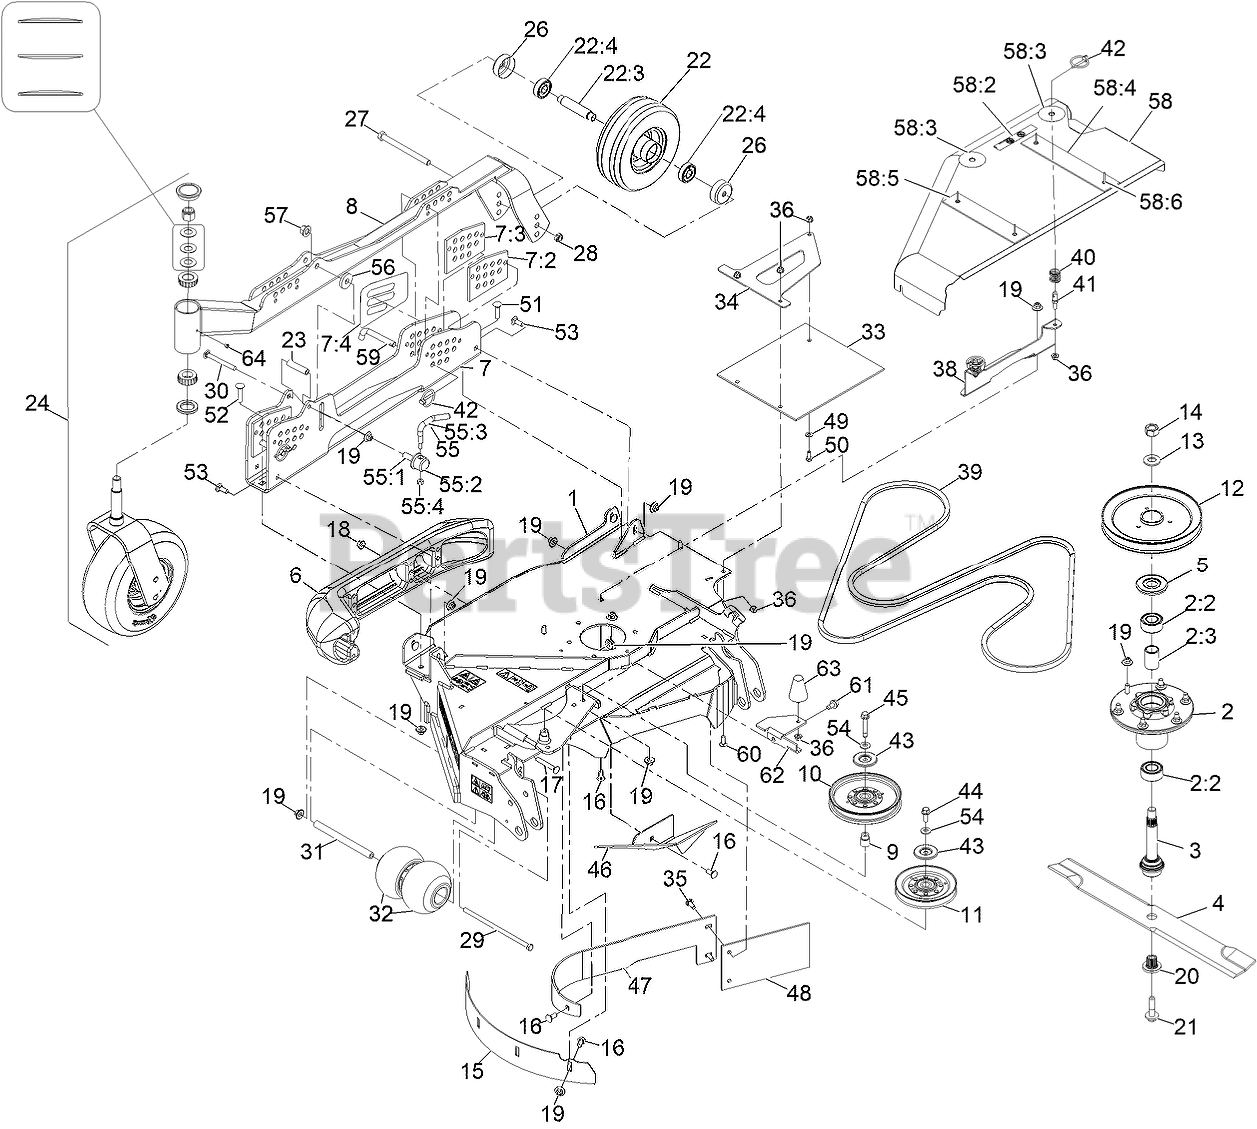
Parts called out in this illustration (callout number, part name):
1	ASM-DECK, RH WING 96
2	ASM-CUTTER HSG
2:2	BEARING-3205 TRASHGUARD
2:3	SPACER-BEARING
3	ASM-SPINDLE AND SEAL
5	GUARD-BEARING, TOP
6	SKID-BUMPER, DECK
7	RH HOC CHANNEL ASM
7:2	PLATE-GUIDE, HOC (LH)
7:3	PLATE-GUIDE, HOC (RH)
7:4	DECAL-HEIGHT OF CUT, RH
8	CALL CUSTOMER SERVICE
9	BUSHING-IDLER
10	IDLER-PULLEY
11	IDLER-V
12	SHEAVE-SINGLE 96RD
14	NUT-HEX
15	BAFFLE-DEPTH, RH
16	BOLT-CARR
17	SCREW-CARR
18	NUT-HF, NI
19	Nut-Nyloc 3/8-16 Flg
20	BUSHING,SPLINED
21	SCREW,SEMS 1/2-20 X 2.19
22	WHEEL AND TIRE ASM
22:3	AXLE-CASTER
22:4	BEARING
24	ASM-CASTER,11" TIRE
26	GUARD, SEAL
27	SCREW-HH
28	NUT-HEX
29	SCREW-HH
30	SCREW-CARR
31	SPACER-WHEEL
32	ROLLER-SCALP, ANTI
33	GUARD-TIRE
34	SUPPORT-FLAP, RH
35	SCREW-CARR
36	NUT-HF, NI
38	BRACKET-SHIELD MOUNT, OUT
41	PIN, SPRING
42	PIN-LYNCH
43	SHIELD-DUST
44	SCREW-HHF 3/8-16 X 1
45	SCREW-HHF
46	BAFFLE-DEFLECT, RH
47	BAFFLE-DOGLEG, RH
48	FLAP-RUBBER
49	WASHER-PLAIN
50	SCREW-HH
51	SCREW-CARR
52	SCREW-CARR
53	BOLT-CARR
54	WASHER-BELLEVILLE
55	LEVER ASM
55:1	SCREW-LOCK
55:2	CAP-LOCK
55:4	NUT-LOCK, NI
57	Nut-Lock 1/2-13
58	ASM-Wing Shield RH
58:2	DECAL-NO STEP
58:3	DECAL-SCRATCH COVER
58:4	Plate-Uhmw 2"
58:5	PLATE-FRONT
58:6	Rivet-Pop
59	PIN-HOC
60	BOLT-CARR
61	SCREW-HWH
62	BRACKET-COVER RETAINER
63	BUMPER-RUBBER
